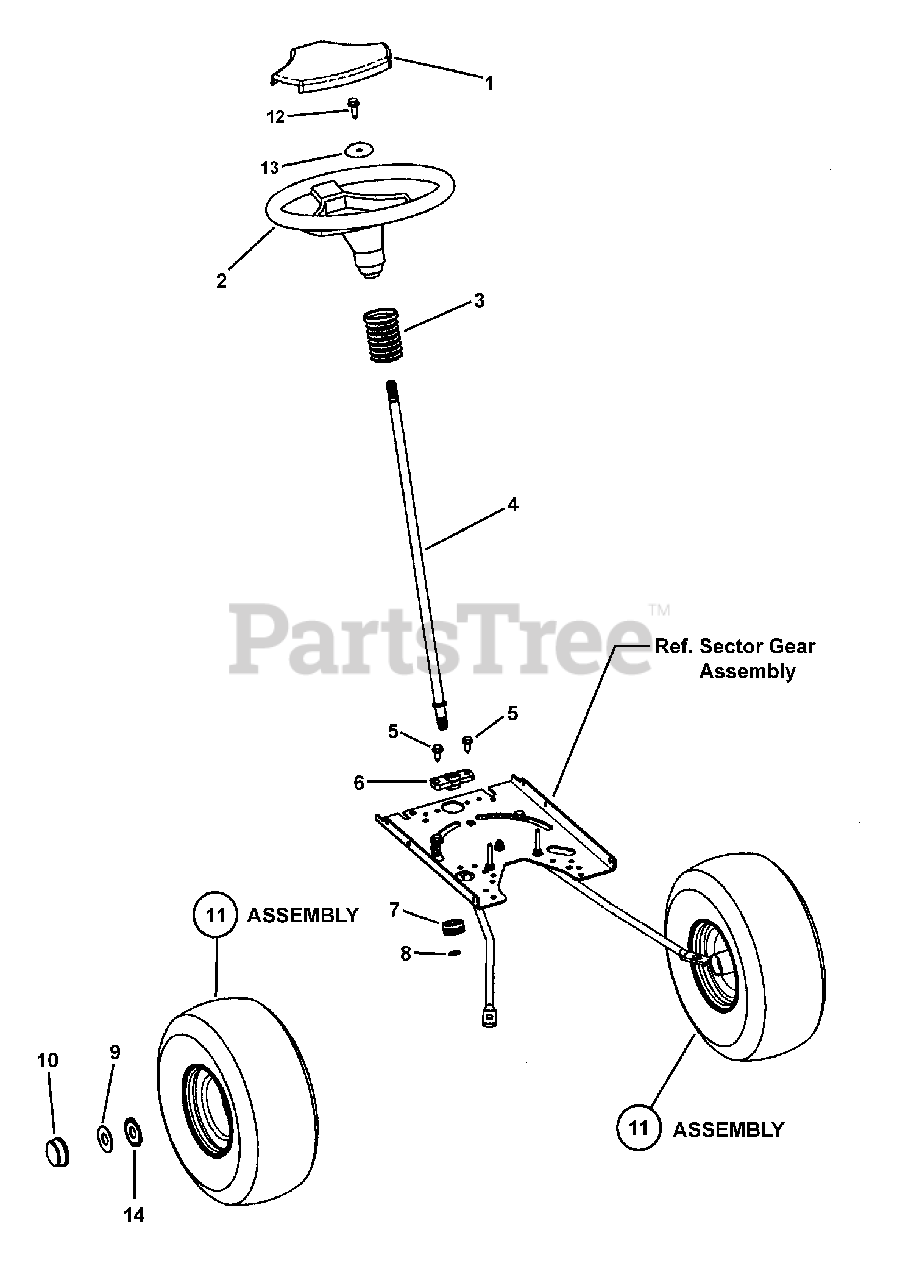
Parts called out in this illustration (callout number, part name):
1	COVER, Integra
2	STEERING WHEEL, (Soft Rim)
3	BELLOWS, Steering Post
4	STEERING POST, 24.56 Long
5	CAPSCREW, 5/16-18 Hex Washer Face
6	BEARING, Lower
7	GEAR PINION
8	SNAP RING, 0.543 ID
9	FLAT WASHER, 1.862 x .765 x 16 GA
10	HUB CAP
11	WHEEL & TIRE ASSY, 15 x 6.00-6 (includes bushings #7014483)
11	WHEEL & TIRE ASSY, 18 x 6.50-8 (includes bushings #7014483)
12	SCREW, 1/4-20 x 1" Hex Washer Self-Tap
13	WASHER, .34 - 1.2 Flat
14	WASHER, Flat, 3/4 x 1-1/4 x 16GA
